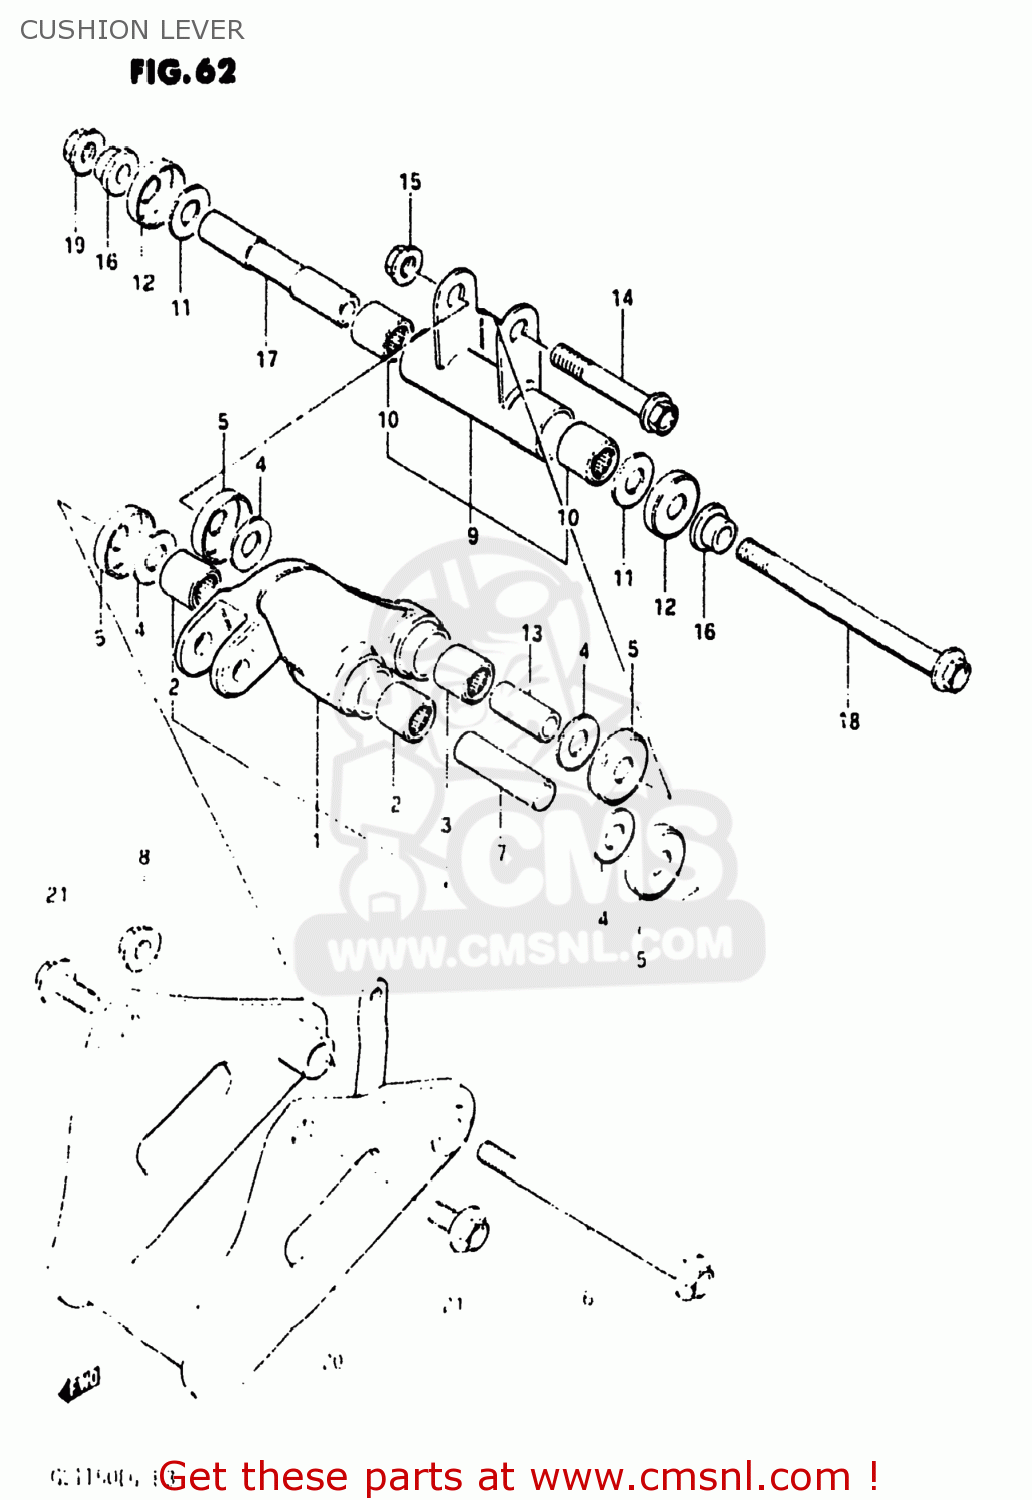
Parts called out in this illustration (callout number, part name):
1	LEVER SET,REAR CUSHION
2	ROLLER BEARING (17X24X2
3	ROLLER BEARING (17X24X25)
4	WASHER
5	COVER,RR SWGARM DUST SEAL
6	BOLT,CUSHION ROD
7	SPACER,REAR CUSHION LEVER
8	NUT 12MM
9	ROD SET,REAR CUSHION,LEFT
10	ROLLER BEARING (17X24X2
11	WASHER
12	COVER,RR SWGARM DUST SEAL
13	SPACER,RR CUSHION LEVER ROD UP
14	BOLT, UPPER
15	NUT 12MM
16	SPACER,REAR CUSHION ROD
17	SPACER,RR CUSHION LVR ROD LOW
18	BOLT,CUSHION ROD
19	NUT 12MM
20	BRACKET,REAR SHOCK ABSORBER
21	BOLT,REAR SHOCK ABSORBER BRACKET
